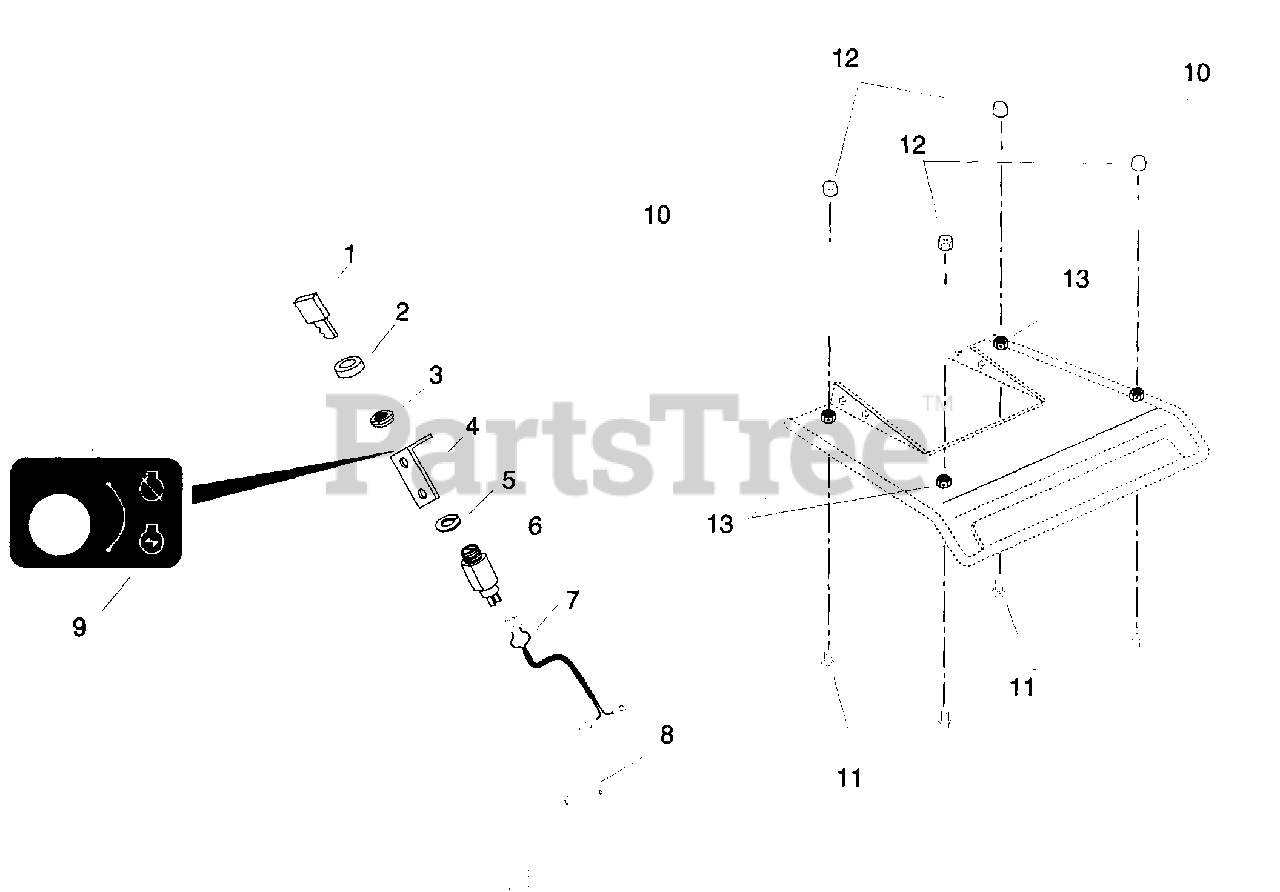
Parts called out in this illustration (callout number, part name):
1	KEY -W/CAP
2	CAP - IGNITION SWITCH
3	NUT-PANEL .625-32 GRECO
4	SWITCH BRACKET - 302
5	WSHR-LK-INT .625X.045 PL
6	KEY SWITCH ASSEMBLY
7	SHORTING WIRE
8	TIE WRAP, BLACK LG 7.31
9	DECAL - TILLER SWITCH
10	SHIELD EXTENSION
11	@BLT-HEX .31-18X.75 GR5 YWZC
12	@NUT-LK-NYL .312-18 YWZC
13	@NUT-LK-CTR .31-18 YWZC
